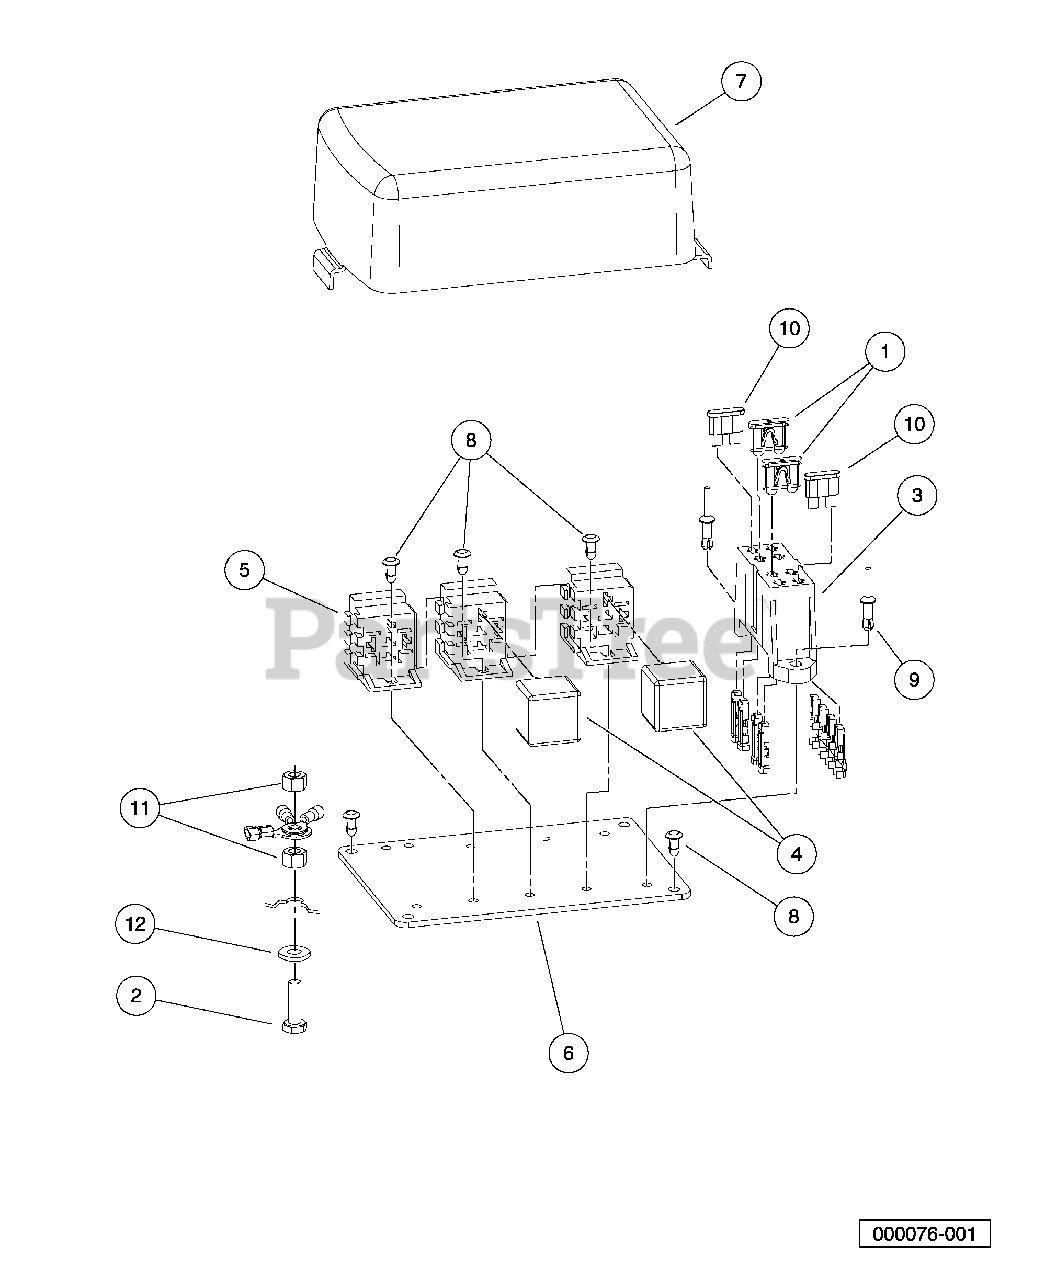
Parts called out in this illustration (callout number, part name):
1	Fuse, 10-Amp
2	Screw, 1/4-20 X .88 Hex Hd Cap
3	Fuse Block
4	Relay, Mini ISO, SPDT
5	Connector, Relay
6	Plate, Electrical
7	Cover, Electrical
8	Fastener, Push-in
9	Rivet, Drive
10	Fuse, 25-Amp
11	Locknut, 1/4-20 Dimpled
12	Washer, 1/4 Type A Narrow Flat
